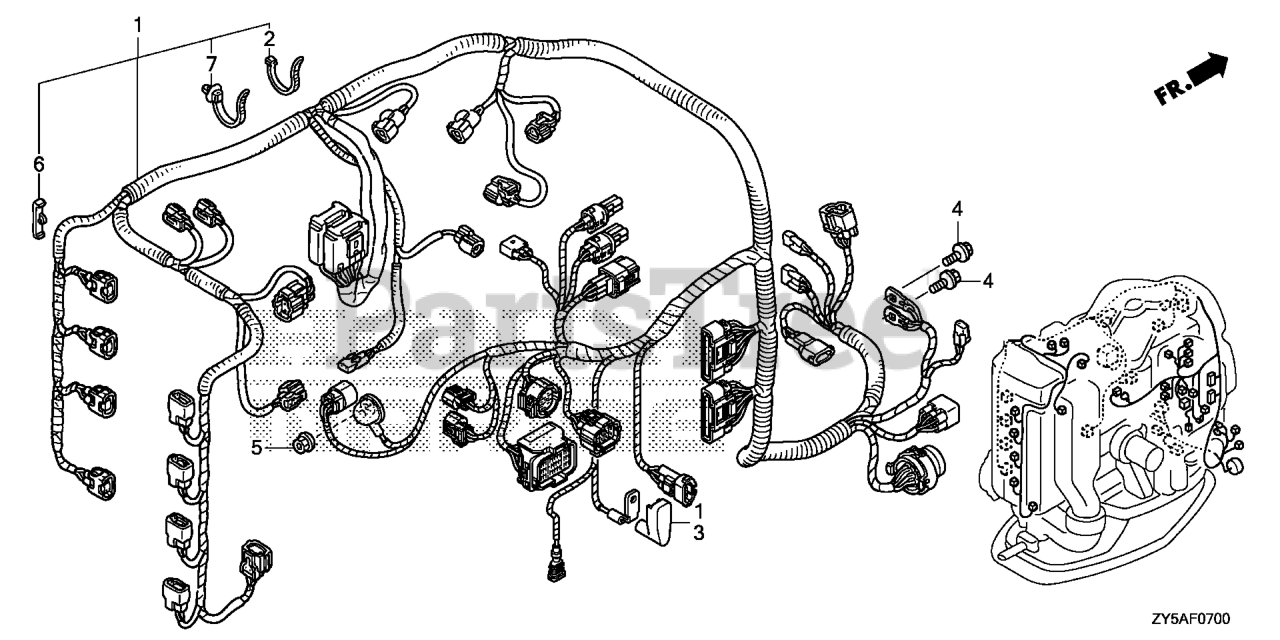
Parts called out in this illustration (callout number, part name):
1	WIRE HARNESS ASSY., MAIN
2	BAND, WIRE
3	COVER B, TERMINAL (L)
4	BOLT, FLANGE (6X12)
5	NUT-WASHER (6MM)
6	CLIP, WIRE HARNESS
7	CLIP, HARNESS BAND (145MM) (BLACK)
